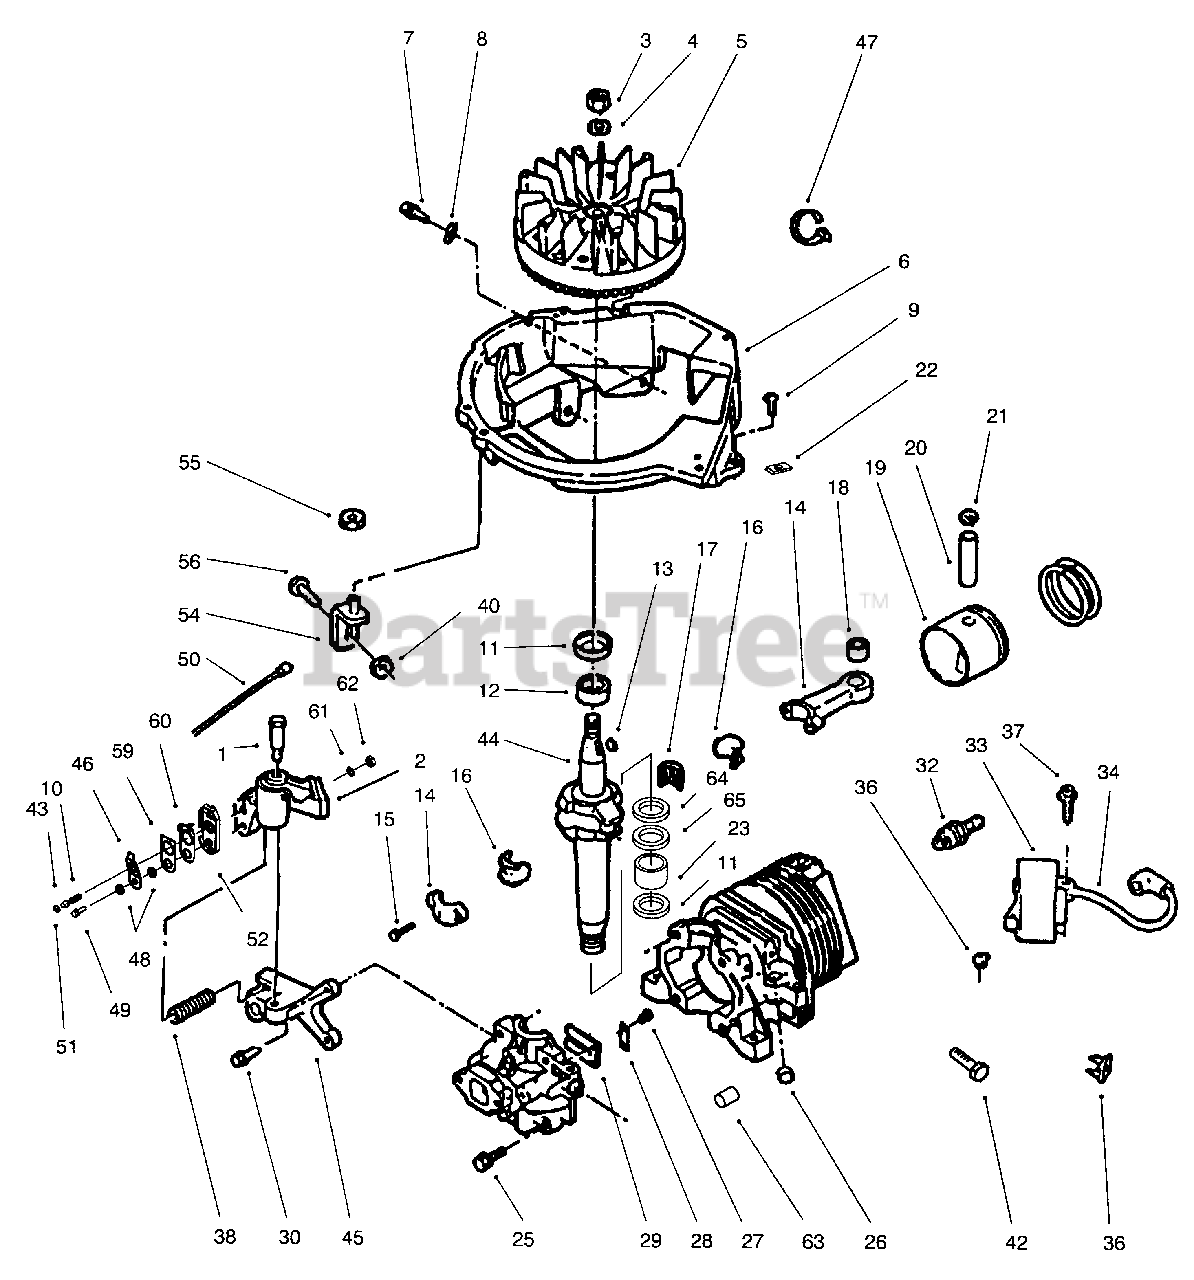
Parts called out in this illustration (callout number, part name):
1	Bolt-Shoulder
2	Brake Assembly
3	Nut-Flywheel
4	Lockwasher
5	Flywheel Assembly
6	Base-Shroud
8	Clip-"J"
10	Spring-Cable Return
11	Oil Seal
12	Bearing-Main-Upper
13	Key-Flywheel
14	Connecting Rod Assy. (Inc 15-18)
15	Screw-Cap
16	Liner-Pair
17	Strip-Roller
18	Bearing Assembly
19	Piston & Ring Set (Inc 20-22)
20	Wrist Pin
21	Retaining Ring
22	Nut-Speed
23	Bearing-Main-Lower
25	Screw-Cover to Crankcase
27	Screw-Reed to Crankcase Cover
28	Plate-Reed Hold Down
30	Screw-Brake Mounting Bracket
32	Spark Plug
33	C. D. Ignition Module & Lead Assy (Incl. Ref. #34)
34	High Tension Lead & Cover
36	Grommet
37	Screw-C. D. Mounting
38	Spring-Brake
43	Actuator-Brake Lever
44	Crankshaft
45	Bracket-Brake
47	Tie Strap
48	Washer
49	Screw-Hex Hd. Cap
50	Lead Assembly
51	Retainer
52	Case-Switch
54	Brace Assembly
60	Plate-Contact
61	Washer-Lock
62	Nut
64	Bearing-Thrust
65	Washer-Thrust
